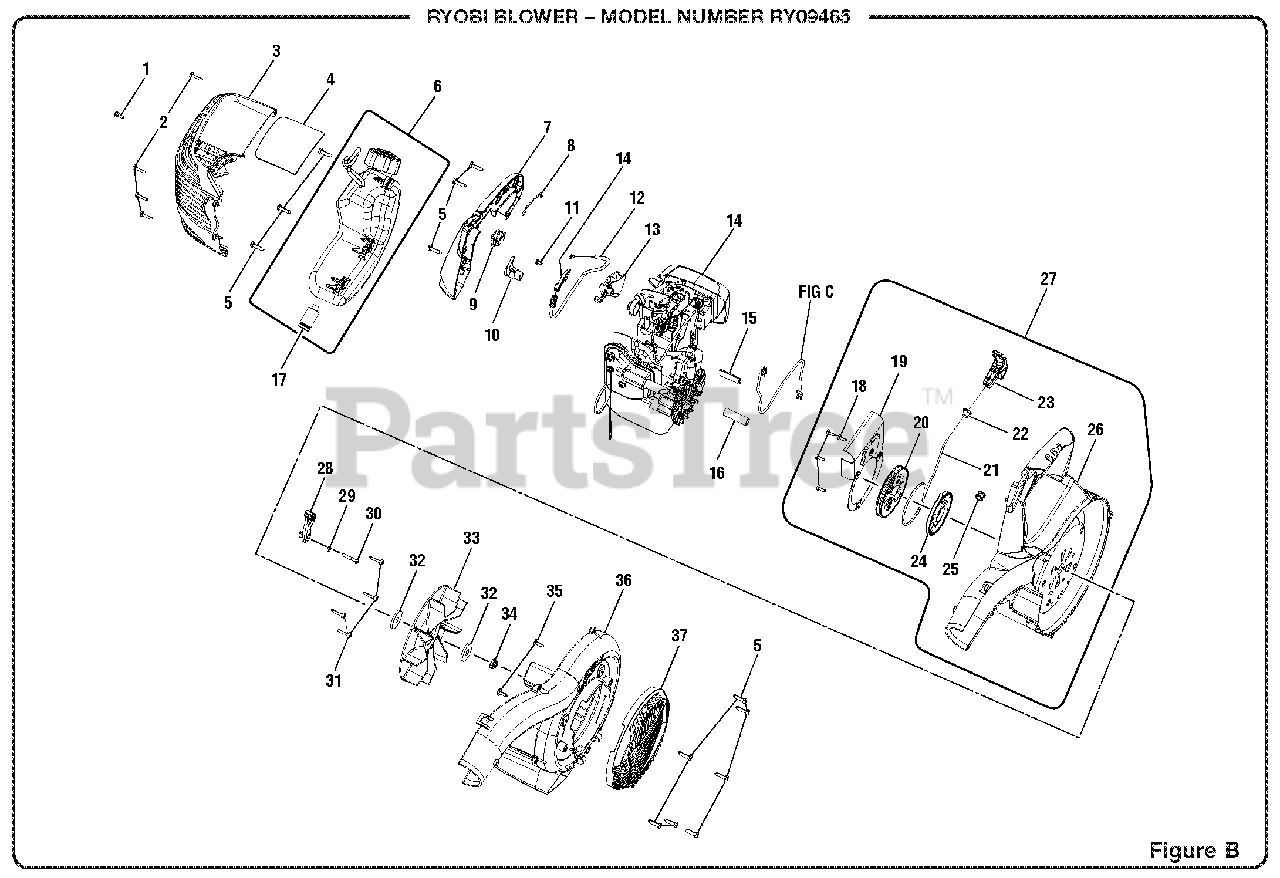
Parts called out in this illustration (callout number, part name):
1	Screw (M5 x 10 mm)
2	Screw (M4 x 18 mm)
3	Engine Housing
4	Heat Shield
5	Screw (10-14 x 3/4 in, T.F.)
6	Fuel Tank Assembly w/Cap
7	Handle Cover
8	Ground Wire
10	Trigger Lock
11	Screw (M3.5 x 7.5 mm)
12	Throttle Cable
14	Power Head Assembly
17	Fuel Filter
18	Screw (M4 x 12 mm)
20	Starter Pulley
21	Starter Rope
23	Starter Grip
24	Container Spring Assembly
26	Inner Volute
27	Lower Housing w/Starter
28	Cruise Lever
30	Cruise Lever Screw
31	Screw (M4 x 23 mm)
34	Lock Nut (3/8 in.)
35	Screw (10-14 x 1/2 in.)
36	Outer Volute
37	Air Inlet Cover
38	Throttle Lever
